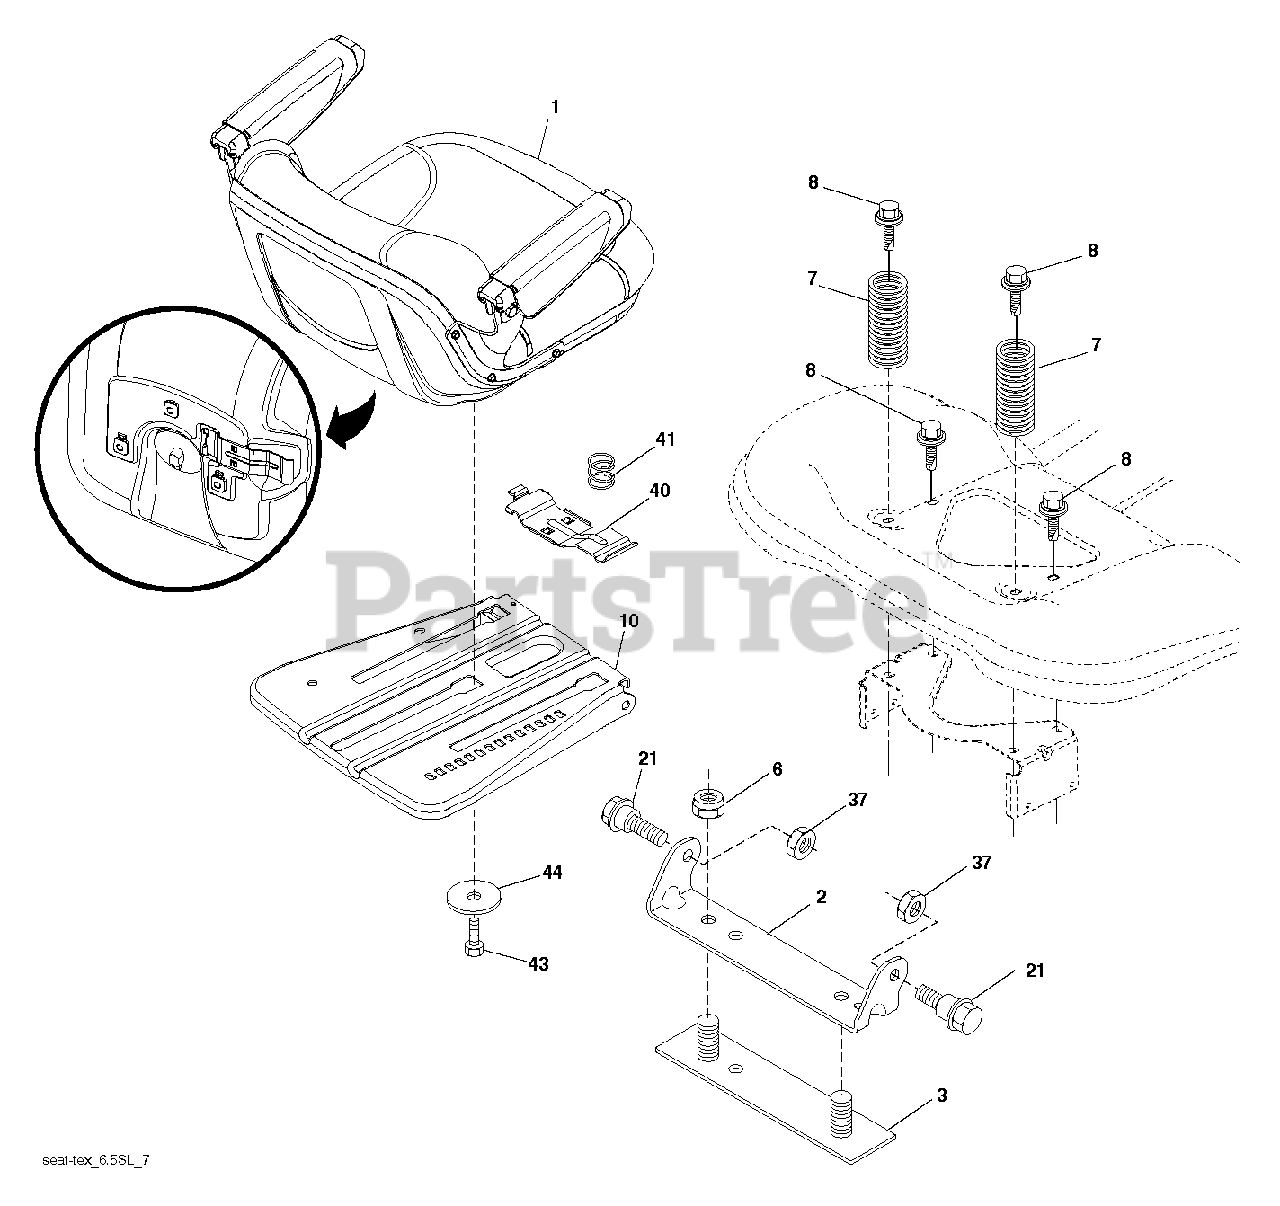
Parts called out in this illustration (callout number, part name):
1	SEAT TP153.TEX.ARMREST PPRO
2	BRKT.PIVOT.FENDER
6	NUT
7	SPRING COMPRESSION
8	BOLT, 5/16-18 X 1 3/4
10	PAN.ASM.SEAT.3PT
21	BOLT.SHOULDER.5/16-18
37	NUT.71038.31-18.HEX.NYLOCK
40	HANDLE.SLIDE.SEAT.TEX.BLACK
41	SPRING.LATCH.SEAT.TEX
44	WASHER 13/32 X 2-3/8 X 12GA
